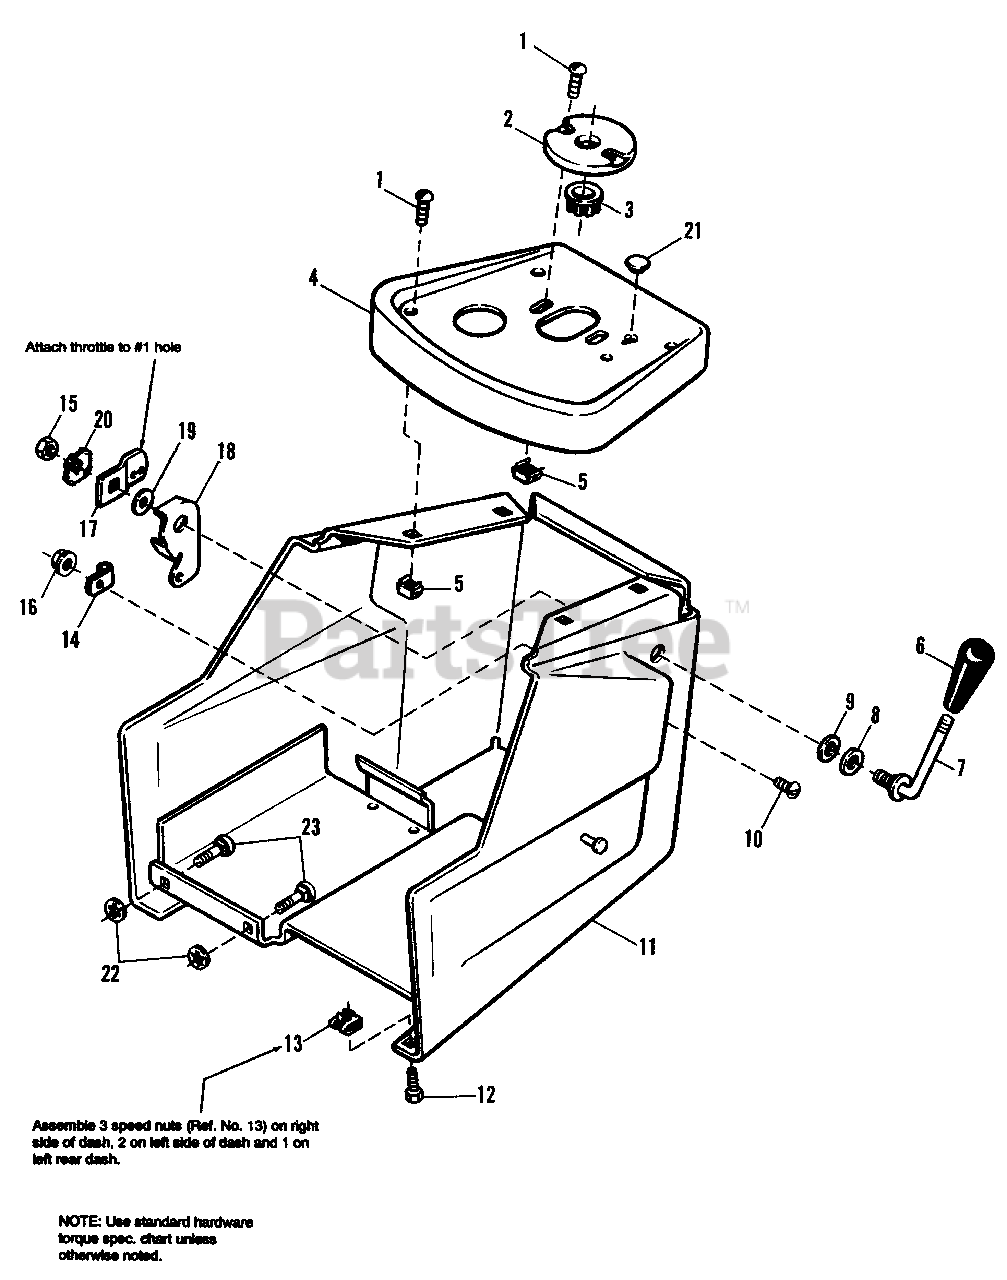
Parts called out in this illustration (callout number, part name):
1	SCREW, Machine, Round Hd., 1/4-20 x 1/2
2	PLATE, Adjusting Steering
4	PANEL Instrument
5	NUT, Tinnerman
6	KNOB, Soft (All except Mfg. Nos. 1692143 & 1692144)
6	KNOB, (Mfg. Nos. 1692143 & 1692144)
7	HANDLE, Throttle Control
10	SCREW, Round Hd., #10-32 x 1/2
11	DASH ASSY. (lncl. Ref. Nos. 22 & 23)
12	SCREW, Hex, Self-tapping, #14AB x 3/4
13	NUT, Speed
14	CLIP, Control Cable
15	LOCKNUT, Hex, 3/8-16
16	NUT, Hex, Washer, #10-32
17	ARM, Throttle
18	STOP, Throttle (Incl. Ref. Nos. 8 & 9)
20	LOCKWASHER, Dished Type, 3/8
21	PLUG, Button
23	CARRIAGE BOLT, 5/16-18 x 3/4
